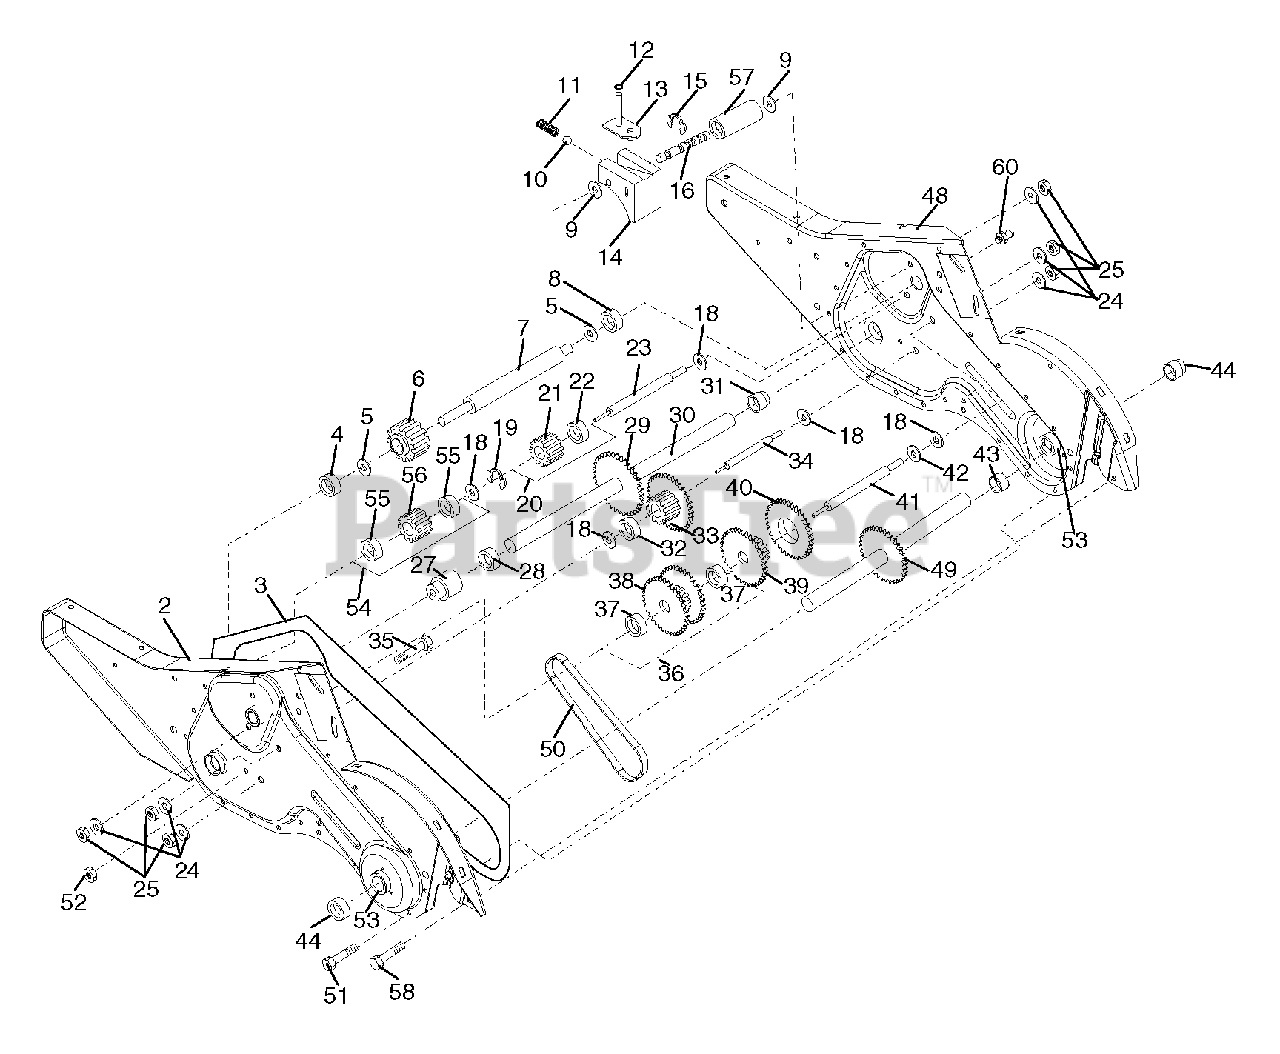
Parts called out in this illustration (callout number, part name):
1	Transmission Assembly
2	Gearcase, L.H. w/Bearing
3	Gasket, Gearcase
4	Bearing, Needle
5	Washer, Thrust 5/8 x 1.10 x 1/32
6	Pinion, Input
7	Shaft, Input
8	Bearing, Needle
9	Washer, Seal
10	Ball, Steel
11	Spring, Shift, Fork
12	O-Ring
13	Arm, Shift
14	Fork, Shift
15	Ring, Klip
16	Shaft, Shift
18	Washer
19	Ring, Klip
20	Gear, Assembly, Reverse Idler
21	Gear, Reverse Idler
22	Bearing, Needle
23	Shaft, Reverse Idler
24	Washer, Lock 7/16
25	Nut, Hex 7/16-20
27	Bearing, Shaft, Ground Drive L.H.
28	Spacer 0.765 x 1.125 x 1.23
29	Chain #35-50 Pitch
30	Ground Shaft Assembly
31	Bearing, Shaft, Ground Drive R.H.
32	Spacer 0.70 x 1.00 x 1.150
33	Sprocket and Gear Assembly
34	Shaft, Reduction (2nd)
35	Screw, Whiz, Lock 5/16-18 x 3-1/2
36	Sprocket Assembly w/Bearing
37	Bearing, Needle
38	Sprocket, Tine
39	Gear, Cluster, Red 1st & 2nd
40	Gear, Reverse
41	Shaft, Reduction (1st)
42	Washer, Thrust
43	Spacer 1.01 x 1.75 x 0.760
44	Seal Asm. OIl
48	Gearcase, R.H. w/Bearing
49	Shaft, Tine
50	Chain, Roller #50-50 Pitch
51	Screw 1/4-20 x 1/2
52	Nut, Hex 5/16-18
53	Bearing Kit, Tine Shaft
54	Gear, DRT Idler w/Bearing
55	Bearing, Needle
56	Gear, DRT Idler
57	Spacer, Split .52 x .64 x 1.04
58	Screw 1/4-20 x .875
60	Fitting Grease
60	Grease, Plastilube #1
